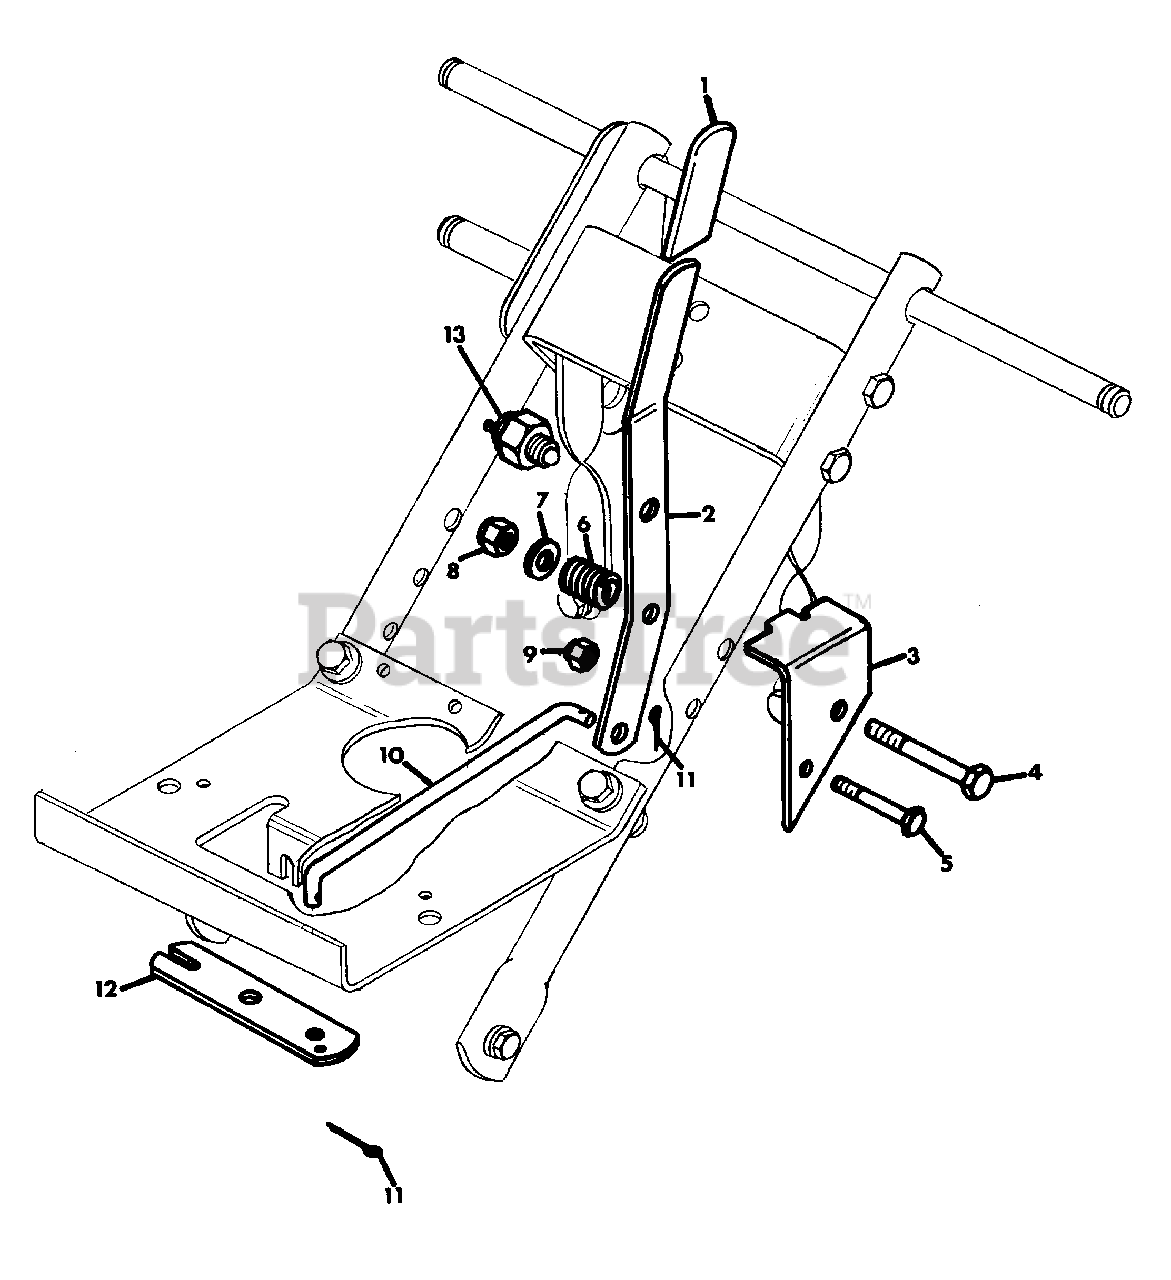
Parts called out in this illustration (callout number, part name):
1	GRIP, HANDLE
3	BRACKET, PTO
4	BOLT, HEX 3/8-16X3.25
5	BOLT, HEX 1/4-20X2.00
6	SPRING, COMP. 1X.78
7	WASHER, FLAT .406X.812X.065
8	NUT, LOCK 3/8-16
9	NUT, LOCK 1/4-20
10	ROD, PTO
11	PIN, COTTER .09X1.00
12	ARM, SHIFTER
13	SWITCH, INTERLOCK
